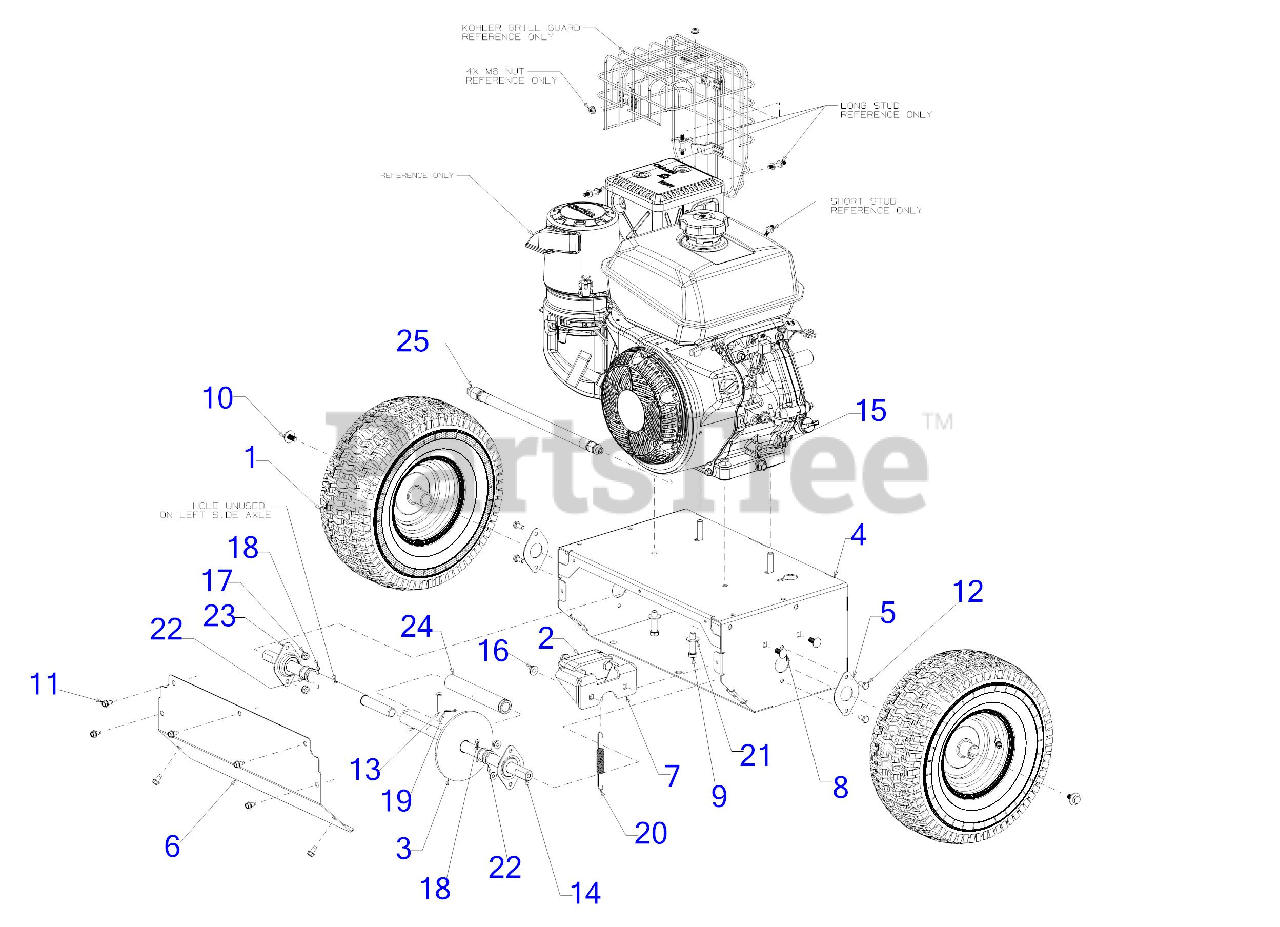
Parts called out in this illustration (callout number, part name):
1	WHEEL ASSEMBLY
2	TRANSFER CASE BRAKE ASSEMBLY
3	ROTOR HUB ASSEMBLY
8	CARRIAGE BOLT 5/16-18 x .75
9	SCREW 3/8-16 x 1.50
10	SCREW 5/16-24 x .750 GR5
11	SCREW 1/4-20 X.500
12	SCREW 1/4-20 x .620 GR5
13	CLEVIS PIN
15	FLANGE LOCK NUT
16	FLANGE NUT
17	LOCK NUT 1/4
18	COTTER PIN-5/32 DIA
19	COTTER PIN-3/32X62
20	EXTENSION SPRING
21	FLAT WASHER
22	FLAT WASHER .750X1.000X.060:HD
23	BALL BEARING
24	AXLE SUPORT TUBE
25	OIL DRAIN HOSE
